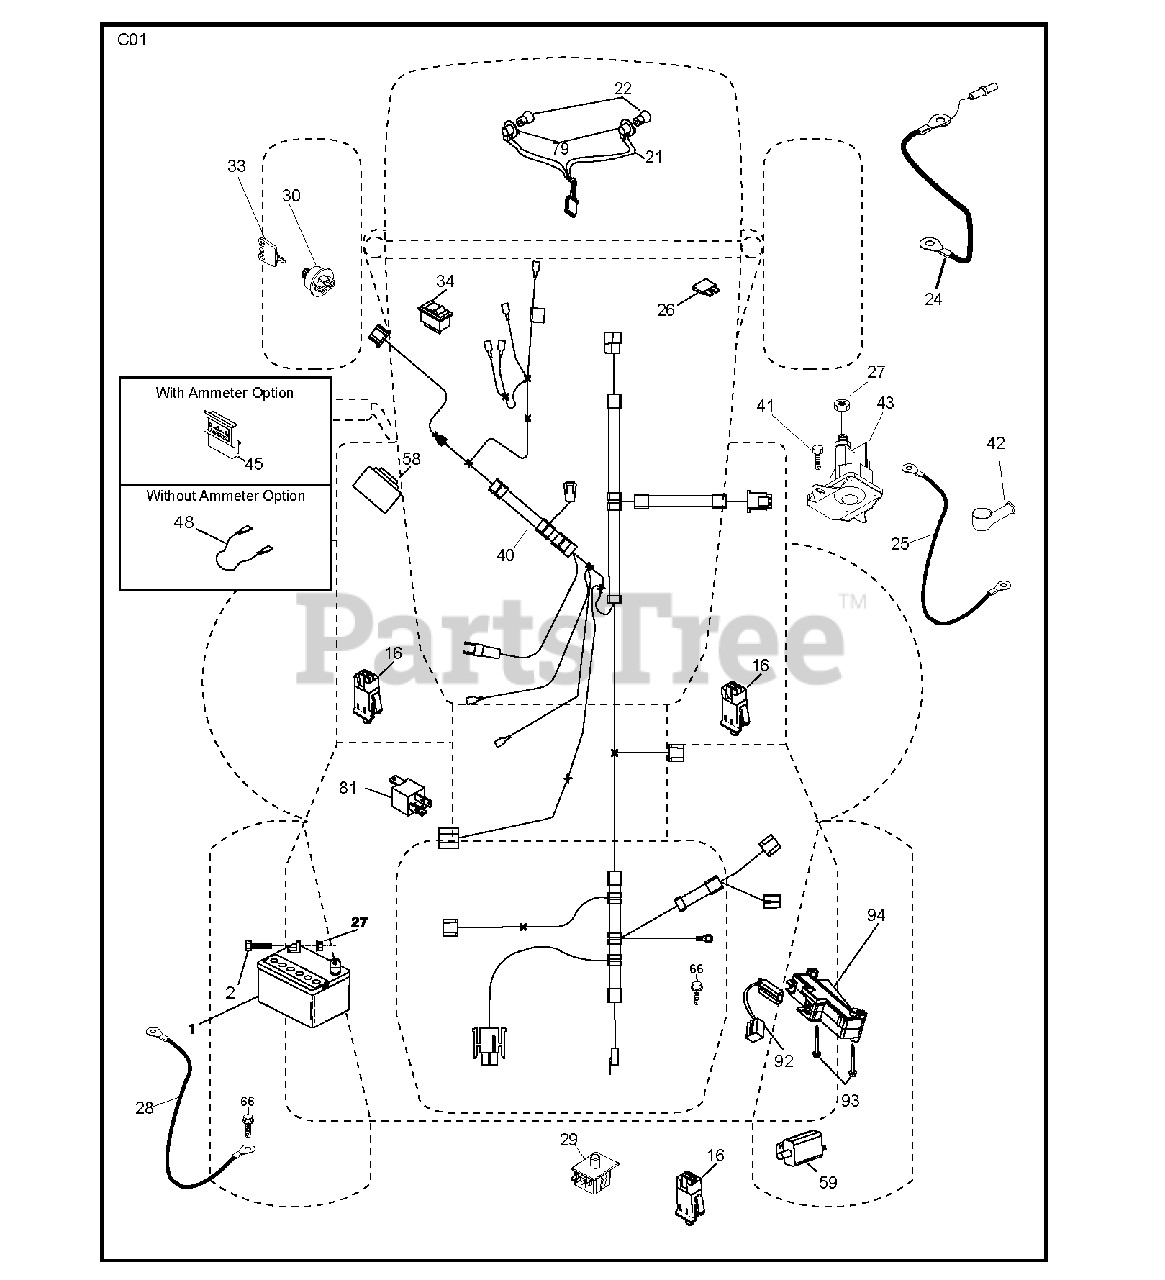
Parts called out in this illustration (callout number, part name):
1	REPL BY 532 12 38-99
16	SWITCH INTERLOOK PUSH-IN
21	HARNESS ASSY LIGHT
22	LIGHTBULB
24	CABLE BATTERY 6 GA. 11" RED
25	CABLE BATTERY
26	FUSE 20AMP
27	NUT
28	CABLE GROUND
29	SWITCH.SEAT.DP W/RAMPS
30	SWITCH.IGN.DELTA.W.LGH.ROS
33	KEY.CHAIN.BLISTER.PACK.GEN.INT
34	SWITCH LT
42	TERMINAL COVER
43	SOLENOID.W/BRASS.PLUNG
58	BUZZER
79	BULB HOLDER ASM.
81	RELAY.ASSY.T
92	HARNESS.PIGTAIL.CONSLE
93	SCREW.PLASTITE
94	MODULE.REVERSE.ROS
